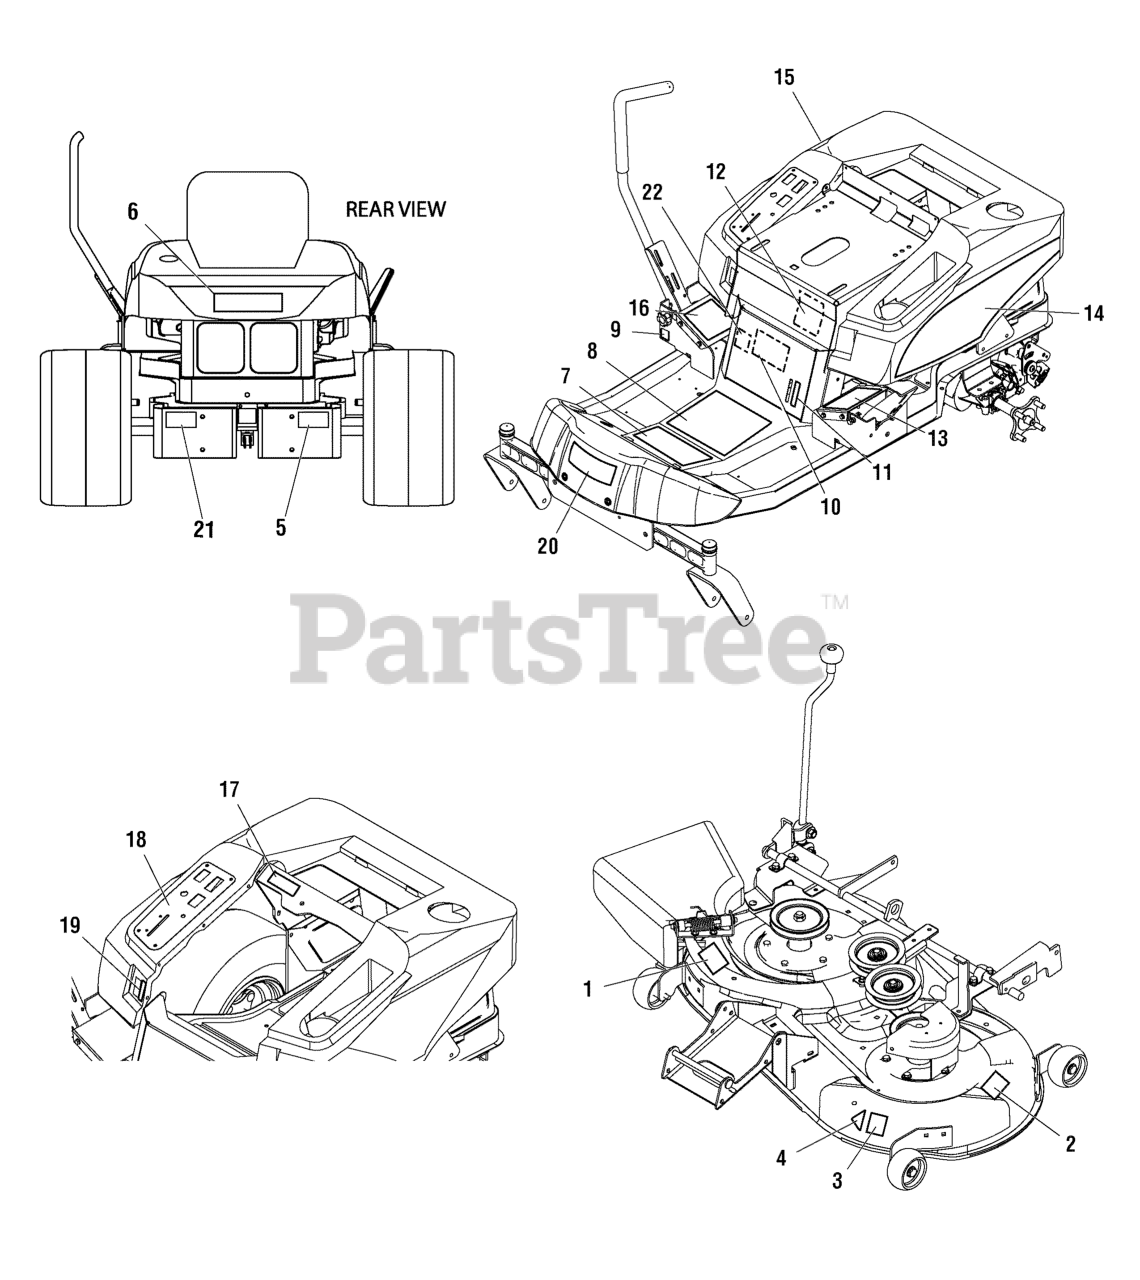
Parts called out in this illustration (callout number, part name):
1	DECAL, Danger Do No Operate without Deflector
2	DECAL, Danger Do Not Put Hands/Feet in Mower
3	DECAL, 42" 2006 Silver/Black
4	DECAL, OPEI Certified ANSI B71.12003 Gold
5	DECAL, Transmission Release Instructions
6	DECAL, Craftsman Logo (Large)
7	DECAL, Operator Instructions Front
8	DECAL, Operator Intructions Bottom
9	DECAL, Tracking Adjustment ZT 7000
10	DECAL, ZTS 7500, 20/42
11	DECAL, Height of Cut
12	DECAL, Belt & Blade
13	DECAL, Handle Control L.H. ZTS 6000
14	DECAL, Seat Deck L.H. Craftsman ZTS
15	DECAL, Seat Deck R.H. Craftsman ZTS
16	DECAL, Handle Control R.H. ZTS 7500
17	DECAL, Do Not Remove Foam Around Engine
18	DECAL, Instrument Panel ZTS 6000
19	DECAL, Height of Cut
20	DECAL, CRAFTSMAN Logo (Small)
21	DECAL, CAUTION, Cut Hazard
22	DECAL, ZT PARKING BRAKE
